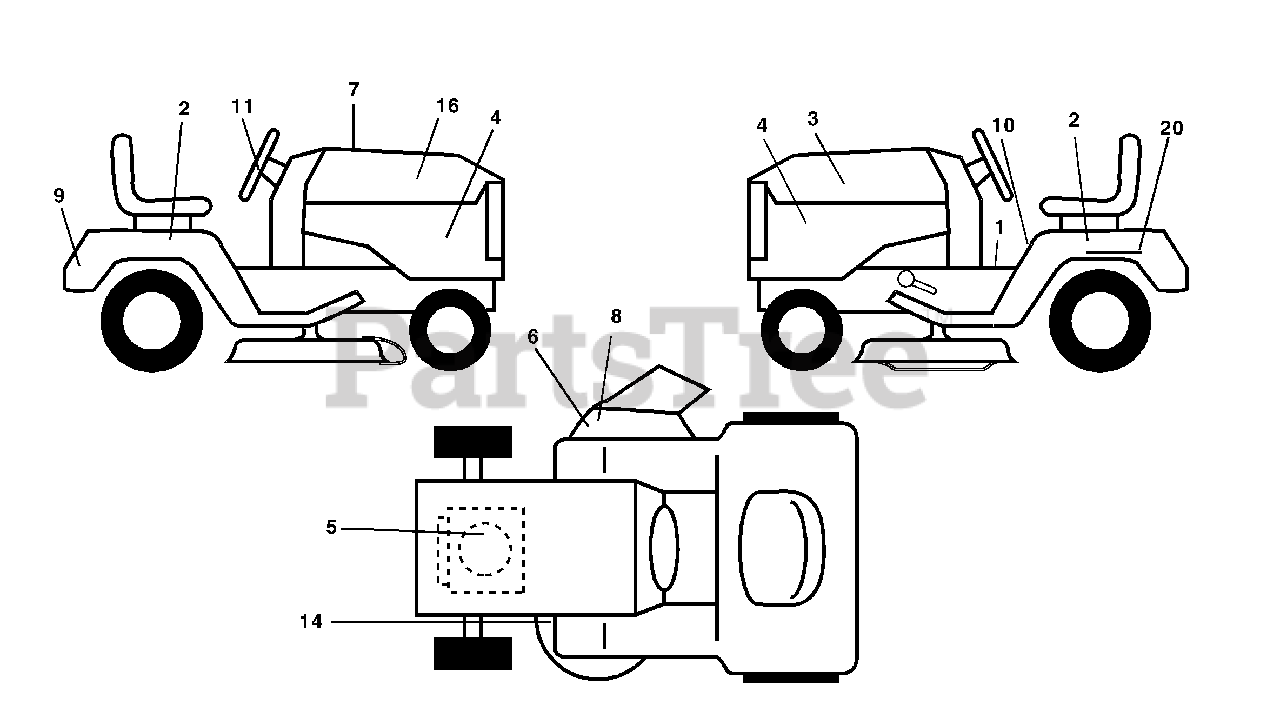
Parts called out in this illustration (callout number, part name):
1	Decal Oper
2	Decal Fender Auto
3	Decal Hood LH
4	Decal Side Panel Logo
5	Decal HP Engine
6	Decal Warning, Keep Hand Away
7	Decal Replacement Parts
8	Decal Deck "B" 42"
9	Decal Fender Logo
10	Decal Fender Danger E/F
11	Decal Ins Strg Whl
14	Decal V-Belt Schematic
16	Decal Hood Rh
20	Decal Bat Dan/Psn
20	Decal By Pass Lt Hydro
